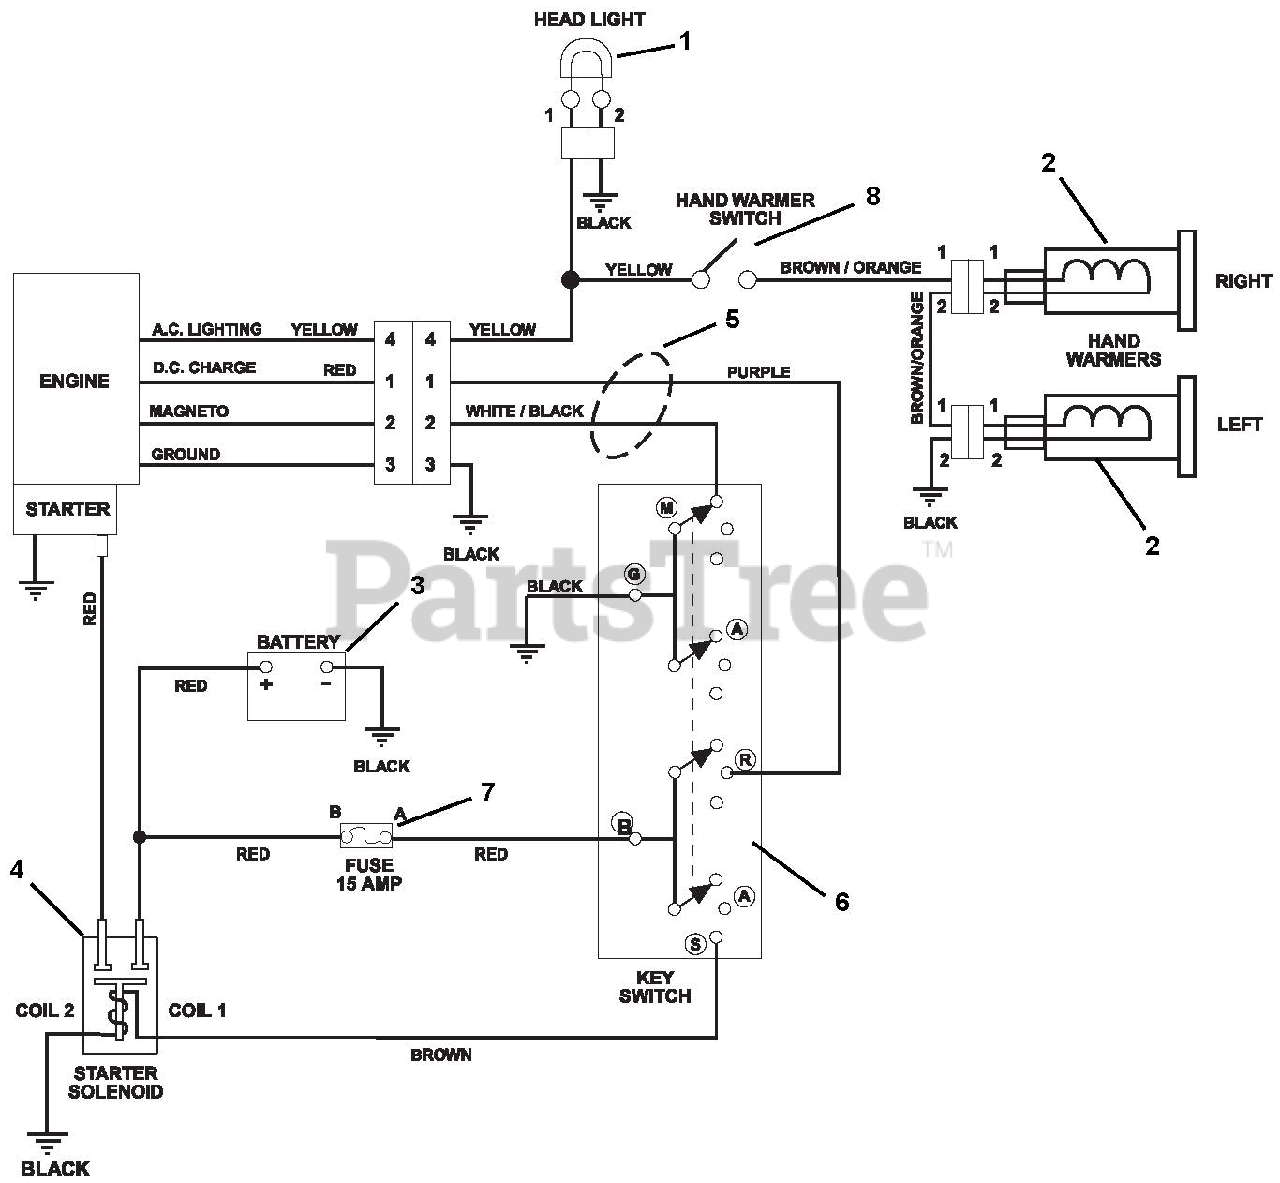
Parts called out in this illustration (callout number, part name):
1	LIGHT, HALOGEN ASSY.
2	HEATED GRIP, MAGURA
4	SOLENOID
5	HARNESS, WIRE-LT, HW, & 12V
6	SWITCH ASSEMBLY
7	FUSE, 15 AMP.
8	SWITCH, ON/OFF
